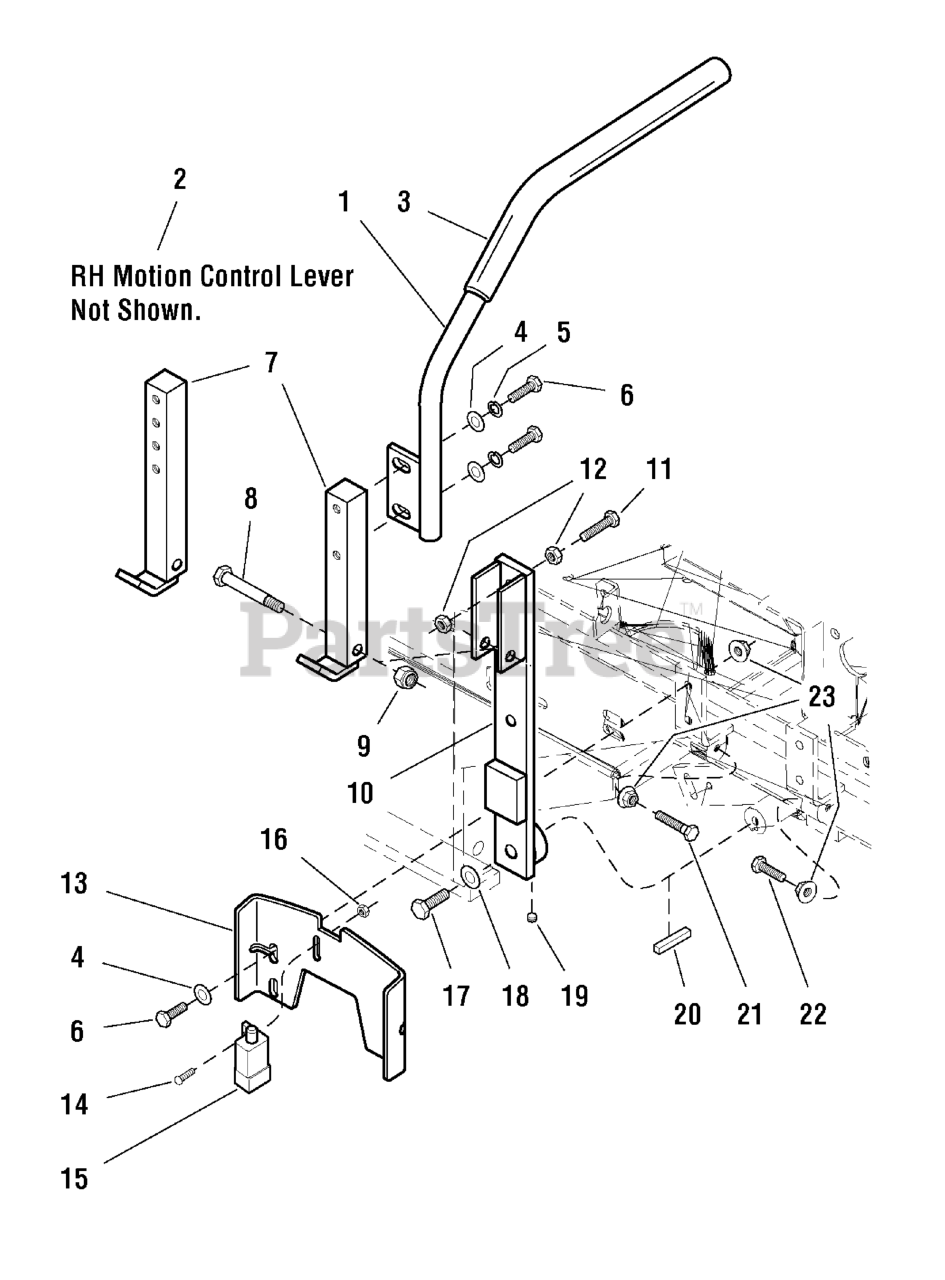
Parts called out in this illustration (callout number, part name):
1	MOTION CONTROL LEVER-RH
3	GRIP, Foam
4	WASHER, 5/16" SAE
5	WASHER, 5/16 LOCK CZ
6	BOLT, 5/16-18 X 3/4 GD5
7	CONTROL LEVER BASE
7	WELD, CONTROL HANDLE BASE
8	BOLT, 3/8-16 X 2, GD5, CZ
9	NUT, 3/8-16 HEX NYLON LOCK
10	CONTROL LEVER MOUNT
11	BOLT, 5/16-18 X 1 GD5 YZ
12	NUT, 5/16-18 HEX
13	NEUTRAL LOCK PLATE
14	SCREW, #10-24 X 1 RS, CZ
15	SWITCH (see electrical group)
16	NUT, #10-24 Hex
17	BOLT, 3/8-16 x 1-1/4 w/ patch
18	WASHER, 3/8 SAE
19	SET SCREW, 5/16-18 x 1/4 w/ patch
20	KEY, 1/4 SQ. X 1
21	BOLT, 5/16-18 x 1-3/4
22	BOLT, 5/16-18 x 1-1/4
23	NUT, 5/16-18 HEX SERRATED FLANGE (SMALL)
